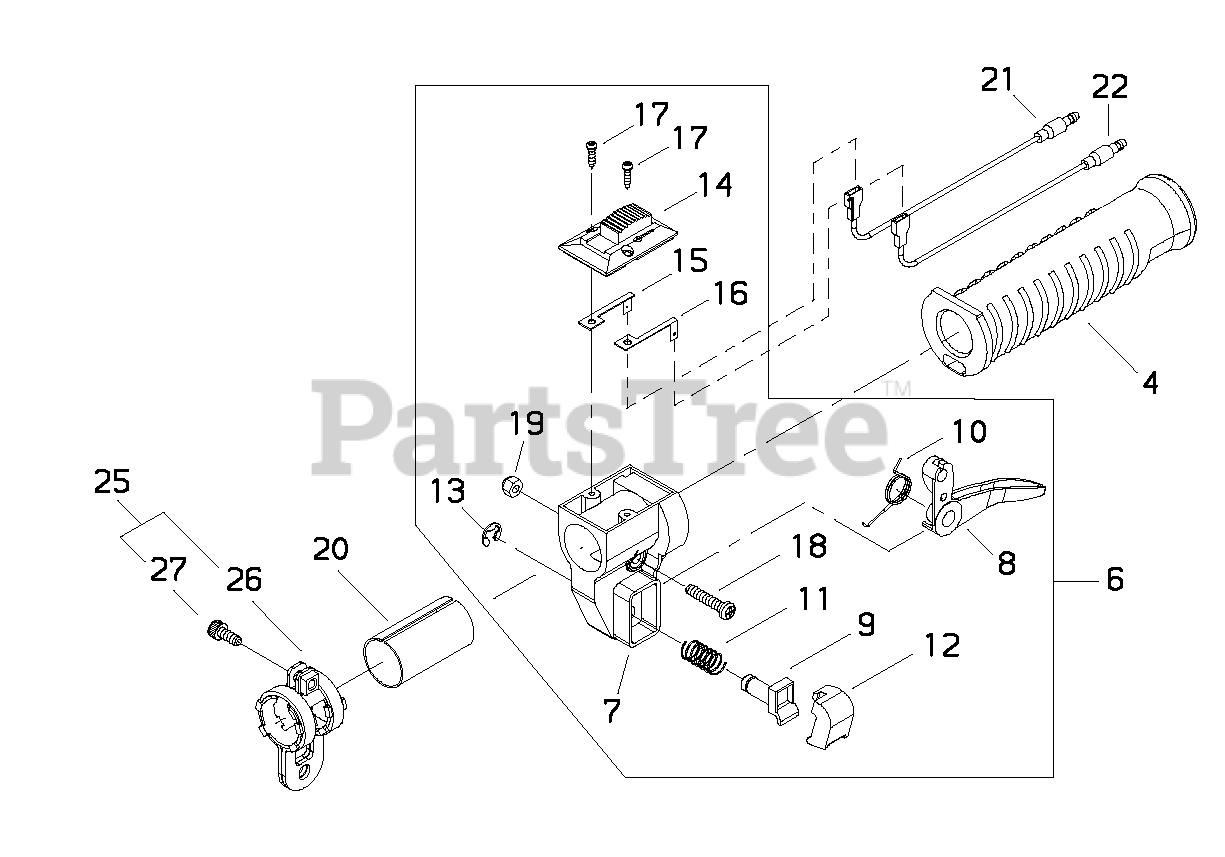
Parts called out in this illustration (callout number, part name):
4	GRIP - REAR
6	THROTTLE CONTROL KIT
7	BODY, THROTTLE
8	TRIGGER, THROTTLE
9	SHAFT
10	SPRING, TRIGGER
11	SPRING
12	BUTTON, THROTTLE LEVER
13	RING, RETAINING
14	SWITCH, IGNITION
15	TERMINAL - GROUND
16	TERMINAL - GROUND
17	SCREW -- TAPPING
18	SCREW - 5X20
19	NUT - NYLON
20	SPACER
21	WIRE - RIGHT
22	WIRE - LEFT
25	HANGER ASSY
26	HANGER
27	SCREW - 5X12
